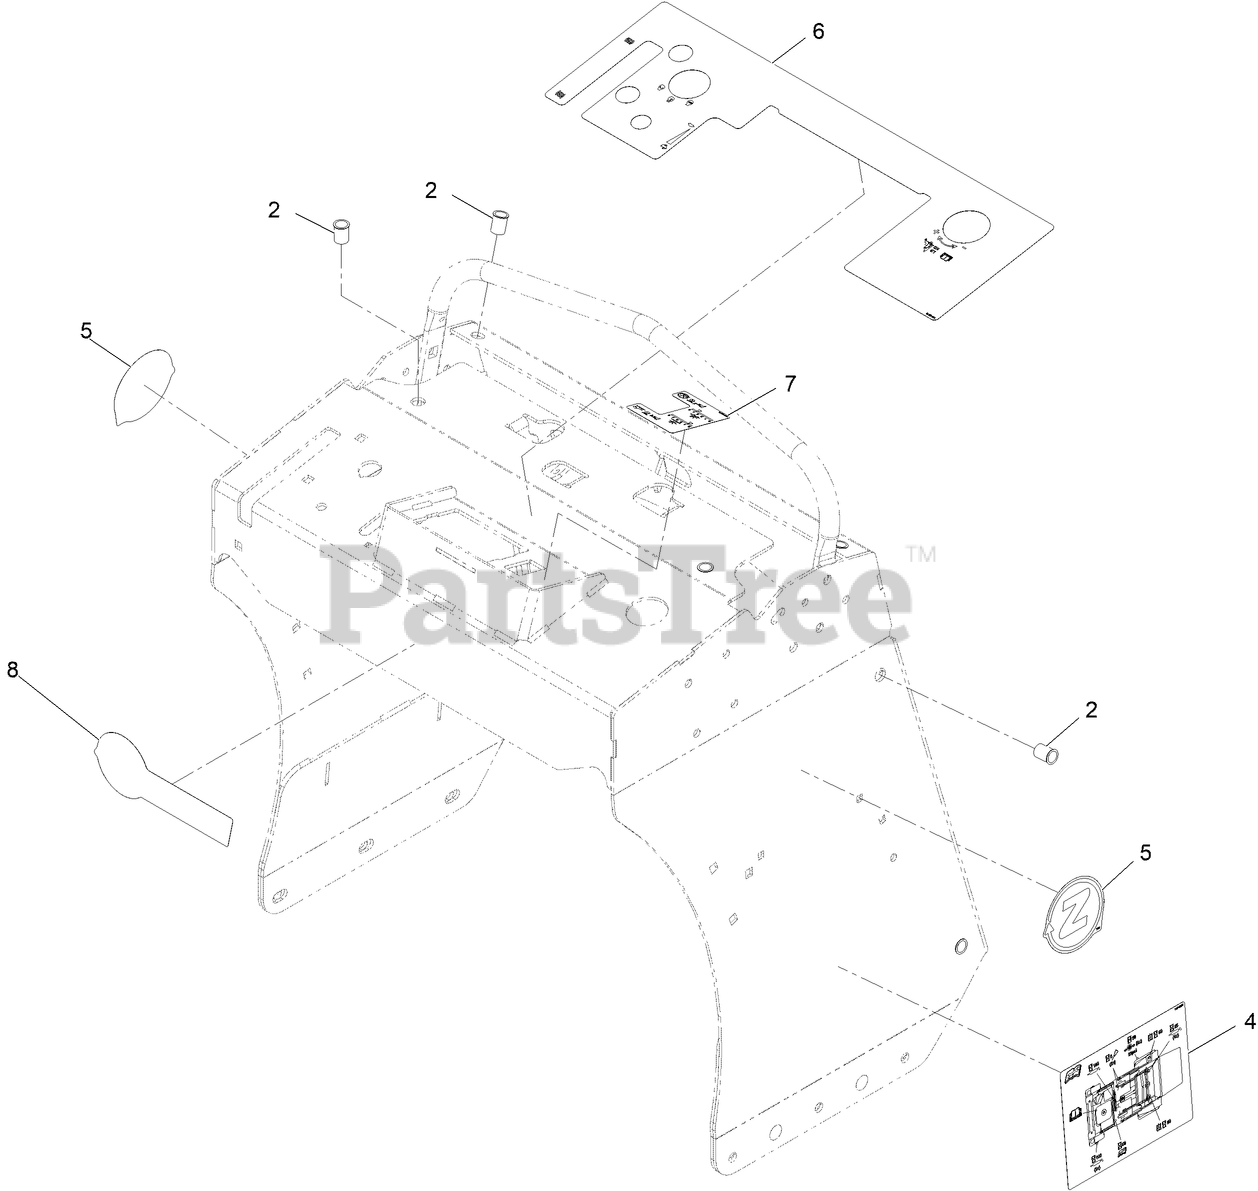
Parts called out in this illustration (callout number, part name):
2	NUT-CLINCH
4	DECAL-AID, SERVICE
5	Decal-Z-Logo
6	DECAL-PANEL, CONTROL
7	DECAL-CONTROL, TINE
8	DECAL-Z-AERATE 24 LOGO
